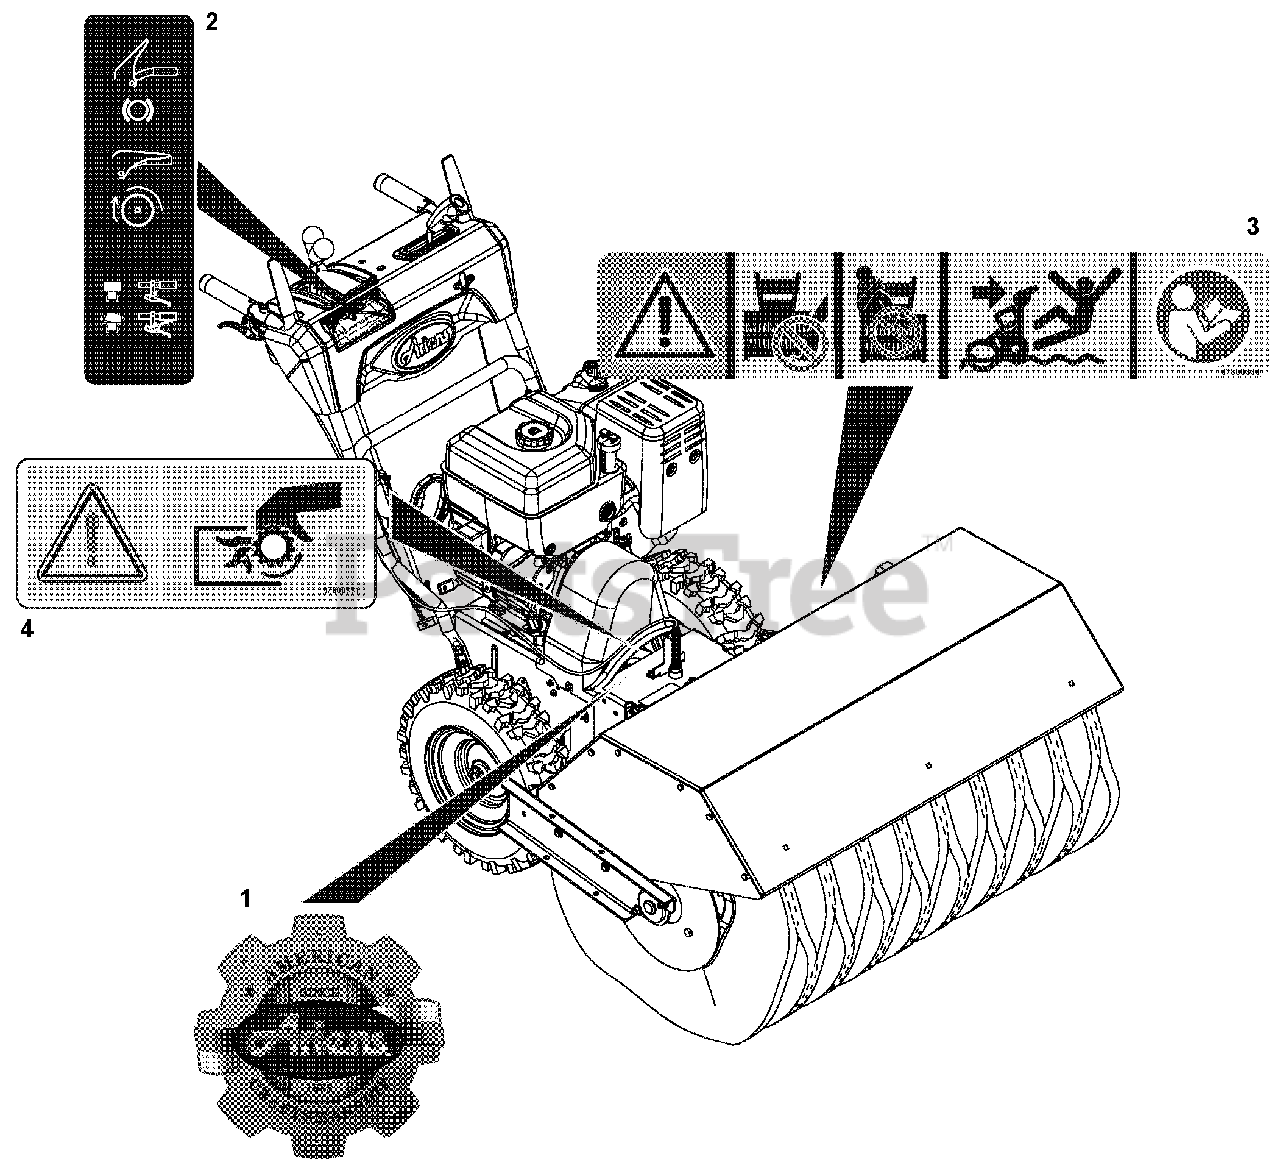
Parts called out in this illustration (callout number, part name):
1	Decal, Ariens Heritage - Large
2	DECAL, CONTROL-BRUSH ANGLE
3	DECAL, DANGER -POWER BRUSH-CE
4	DECAL, PTO WARNING
